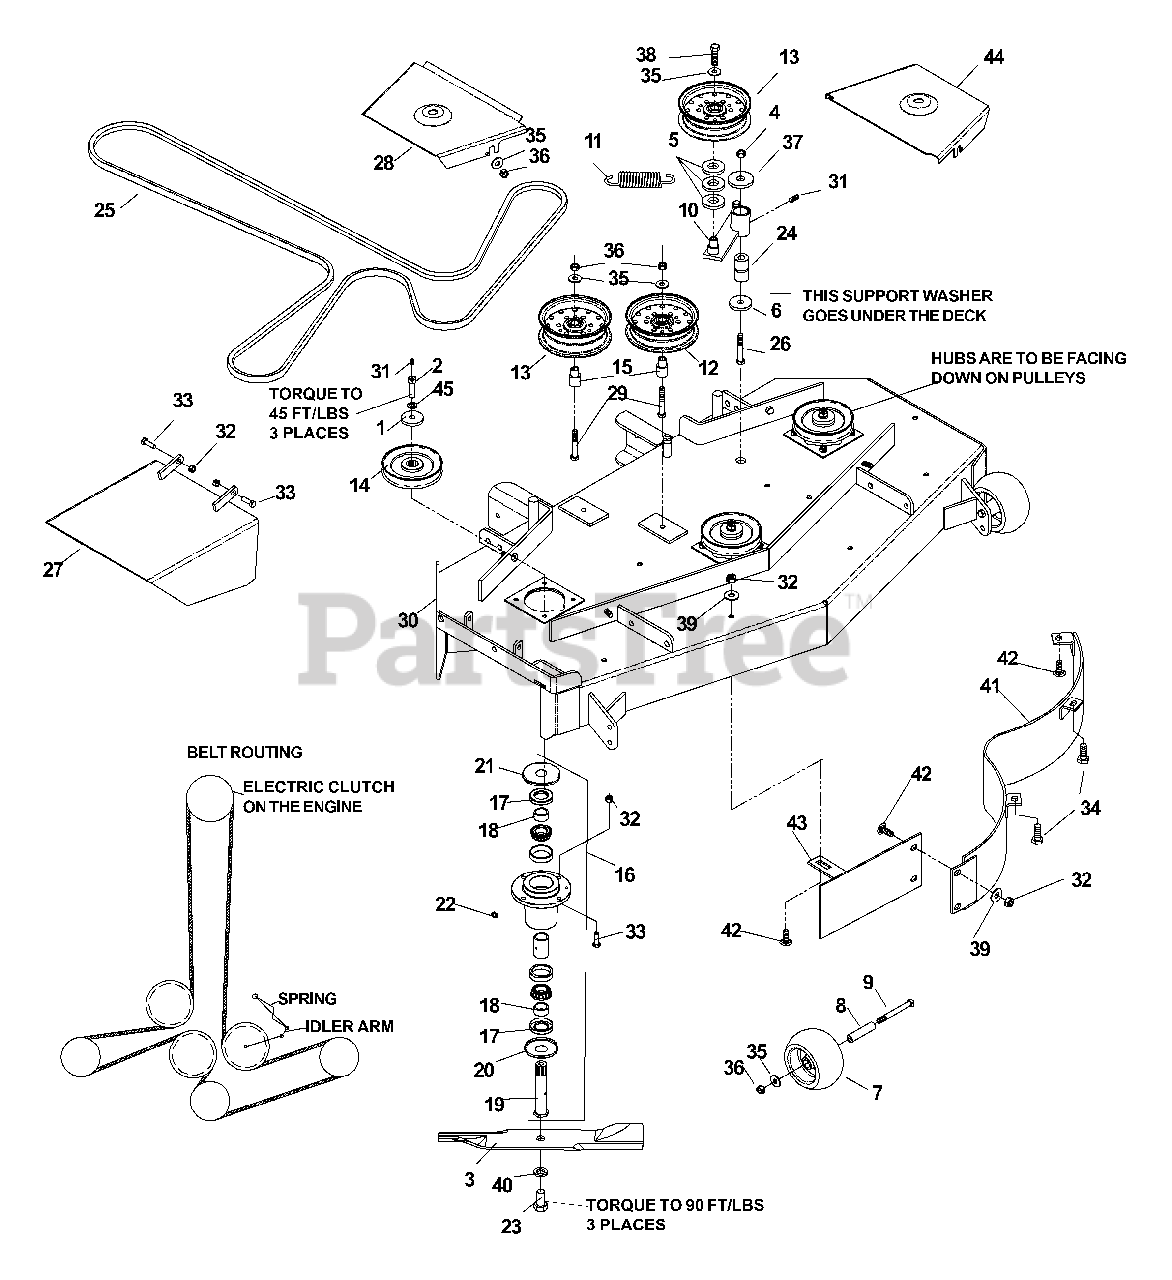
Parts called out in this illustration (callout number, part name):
1	HEAVY WASHER
2	HCS 7/16-20 X 1 1/2, SPECIAL
3	BLADE 16 1/4"
4	NUT, 1/2-13, NYLOC
5	BUSHING, MACHINE
6	SUPPORT WASHER
7	ANTI-SCALP ROLLER
9	HCS, 3/8-16 X 3 1/2
12	IDLER PULLEY
13	IDLER PULLEY (TALL)
14	PULLEY
15	IDLER BUSHING
16	SPINDLE ASSEMBLY (COMPLETE)
17	SHAFT SEAL
19	SPINDLE
20	DUST CAP, BOTTOM
21	DUST CAP, TOP
22	GREASE POPET
23	HCS, 5/8-18 X 1 1/4
24	PIVOT BUSHING
26	HCS, 1/2-13 X 3 1/4
27	DEFLECTOR CHUTE
28	SHIELD, RIGHT
29	HCS, 3/8-16 X 2 1/2
30	DECK W/DECALS
31	ZERK
32	NUT, 5/16 CENTER LOCK
33	HCS, 5/16-18 X 1
34	HCS, 5/16-18 X 3/4
35	WASHER, 3/8
36	NUT, 3/8-16, CENTER LOCK
37	WASHER, 1/2
38	HCS 3/8-16 X 1, SERR. HD.
39	WASHER, 5/16
40	LOCKWASHER, 5/8
41	BAFFLE, MAIN
42	RHSNB 5/16-18 X 5/8
43	BAFFLE, CENTER
44	SHIELD, LEFT
45	LOCKWASHER, 7/16
